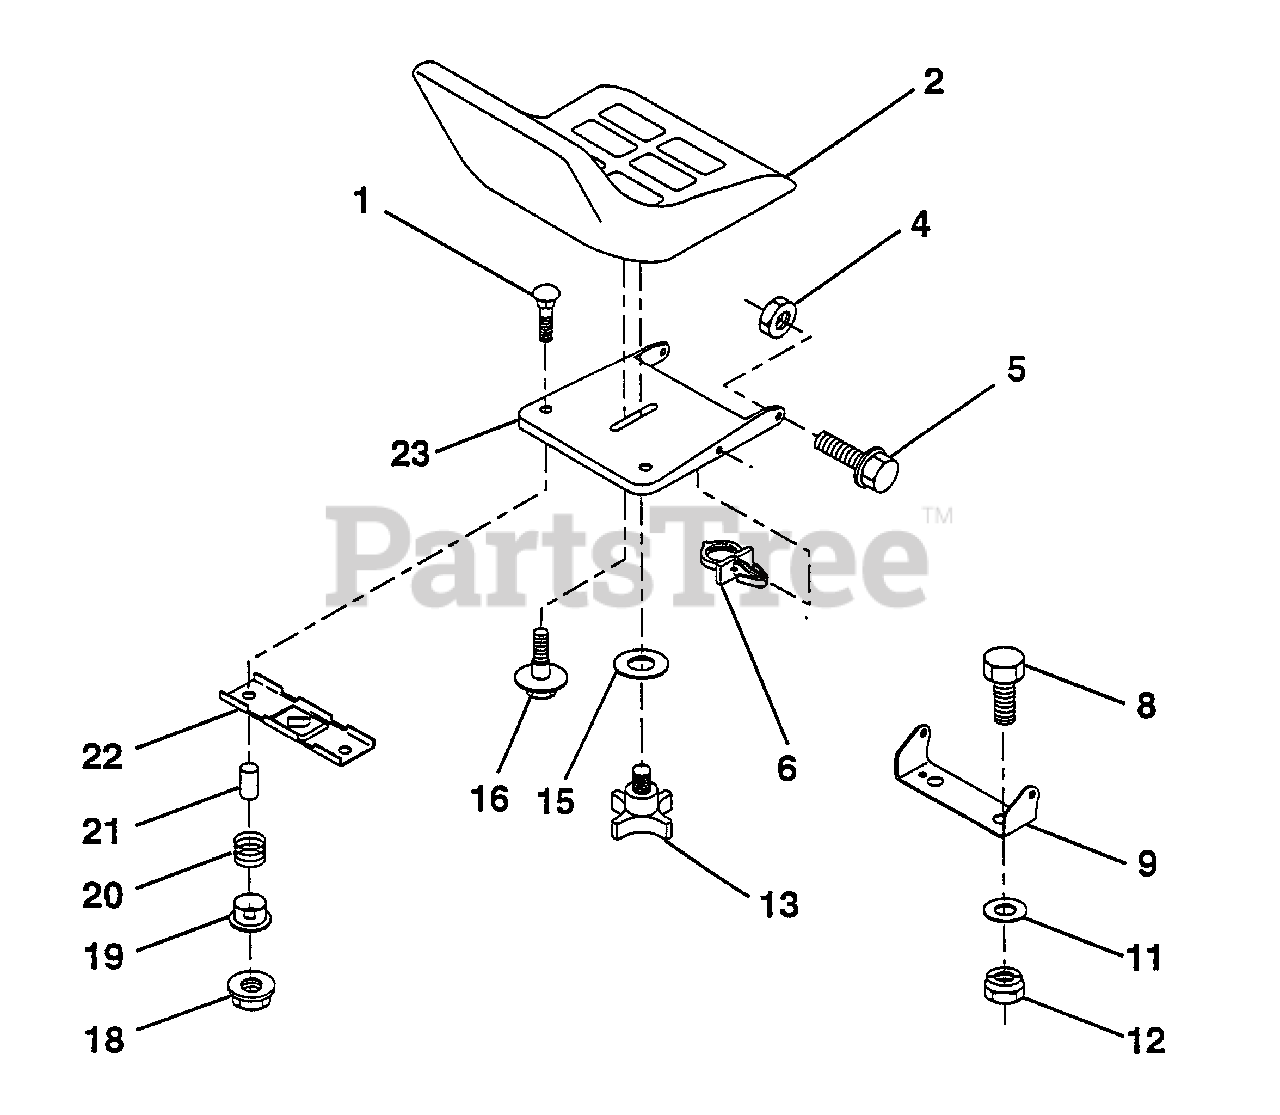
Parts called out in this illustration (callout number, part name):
1	Bolt, Carriage 1/4-20 x 1-3/8
2	Seat
4	Nut, Hex, Lock w/wsh 5/16-18
5	Bolt, Shoulder 5/16-18 UNC
6	Clip, Insulated
8	Bolt, Hex, Fin. 3/8-16 UNC x 1
9	Bracket, Pivot, Seat
11	Washer 12/32 x 2 x 10 Gauge
12	Nut, Hex, Lock Hex w/wsh 3/8-16
13	Knob, Seat
15	Washer 17/32 x 1-3/16 x 12 Gauge
16	Bolt, Shoulder
18	Nut, Hex, Large, Flange Lock
19	Bushing, Snap
20	Spring, Compression
21	Spacer, Split, Large .28 Id. x .96
22	Bracket, Switch Mounting
23	Pan, Seat
